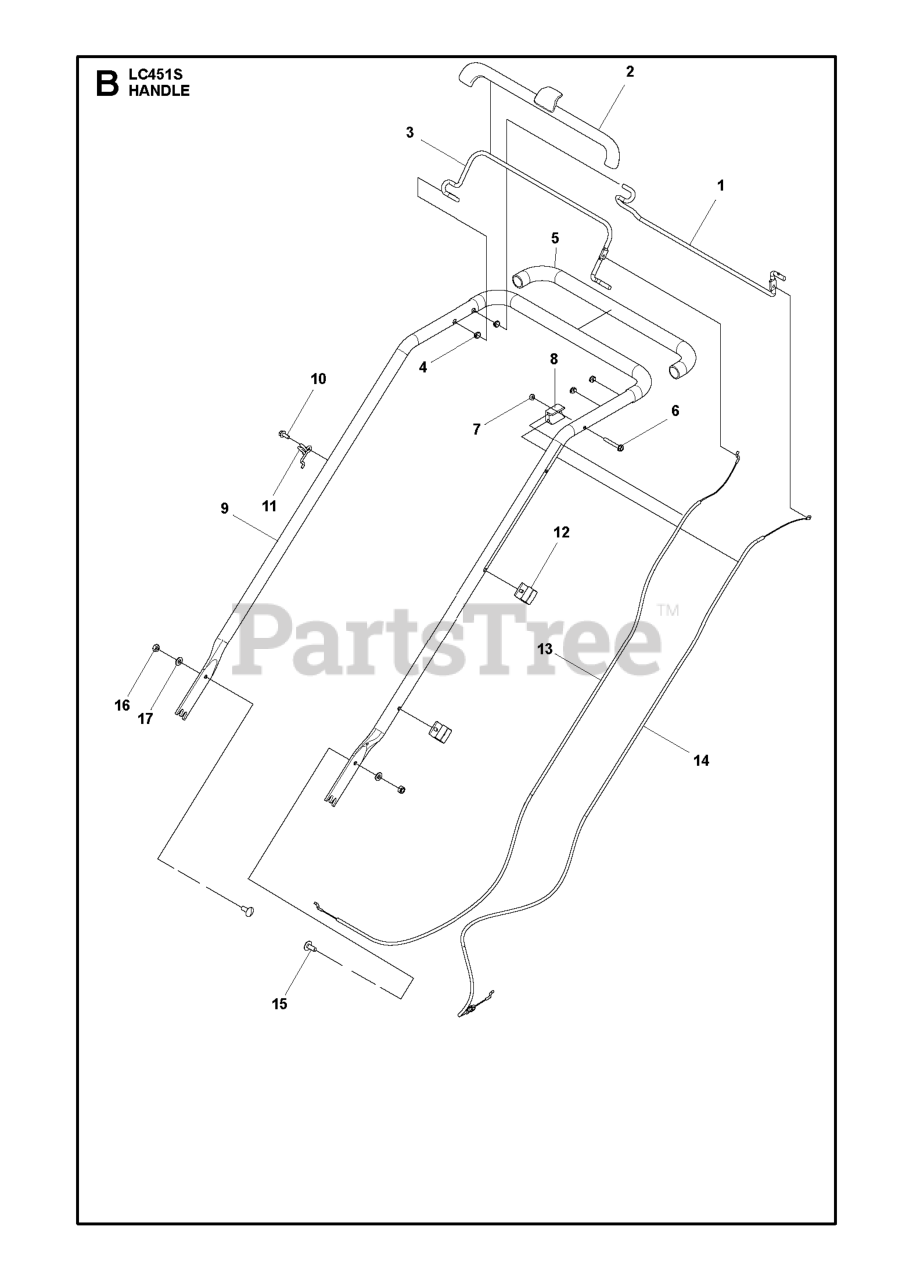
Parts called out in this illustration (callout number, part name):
7	NUT FLANGE - M6
10	SCREW
16	LOCKNUT M8
17	WASHER BRB 8.4X17
